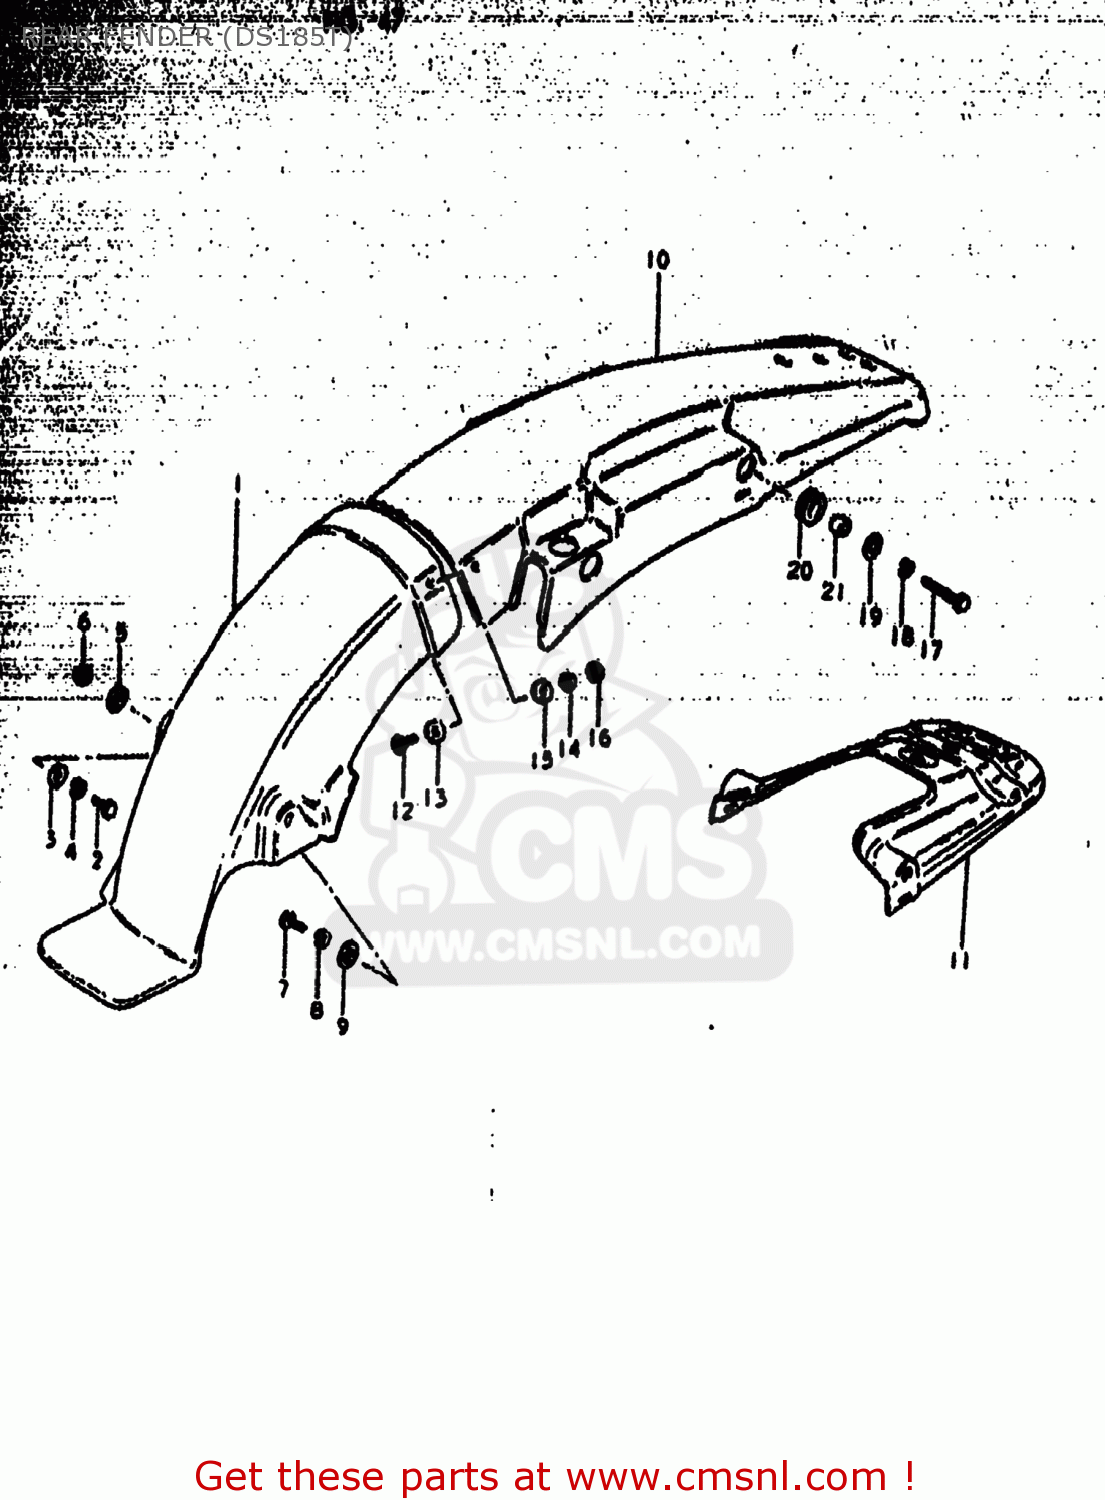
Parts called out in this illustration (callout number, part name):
1	FENDER,REAR
2	BOLT, UPPER
3	WASHER
4	LOCK WASHER
5	WASHER
6	NUT
7	BOLT
8	LOCK WASHER
9	WASHER
10	FENDER,REAR
11	REINFORCEMENT,RR FENDER
12	BOLT
13	WASHER (5.5X16X1.2)
14	LOCK WASHER
15	WASHER(5.2X16X1)
16	NUT
17	BOLT (8X30)
18	LOCK WASHER
19	WASHER
20	CUSHION
21	SPACER (8.2X12X7.5)
